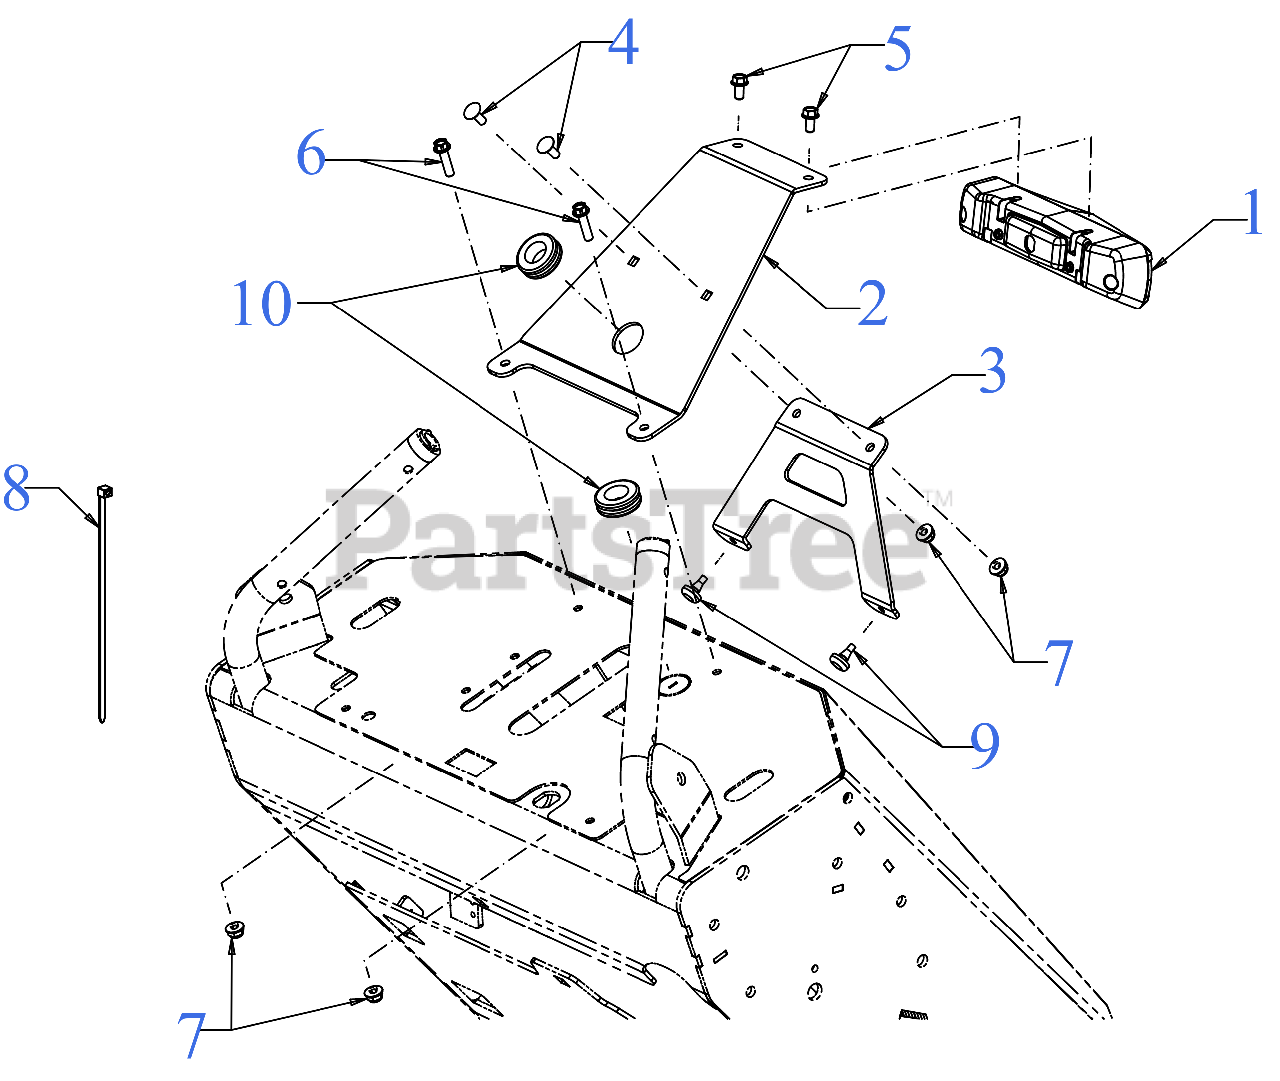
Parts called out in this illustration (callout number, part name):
1	LED LIGHT BAR HEADLIGHT ASSEMBLY
2	LIGHT MOUNT BRACKET
3	SUPPORT BRACKET
4	CARRIAGE BOLT 1/4-20 x .62
5	HEX SCREW 1/4-15 x .50
6	SCREW 1/4-20 x 1.00
7	FLANGE LOCK NUT
8	7" CABLE TIE
9	RUBBER BUMPER
10	RUBBER GROMMET
